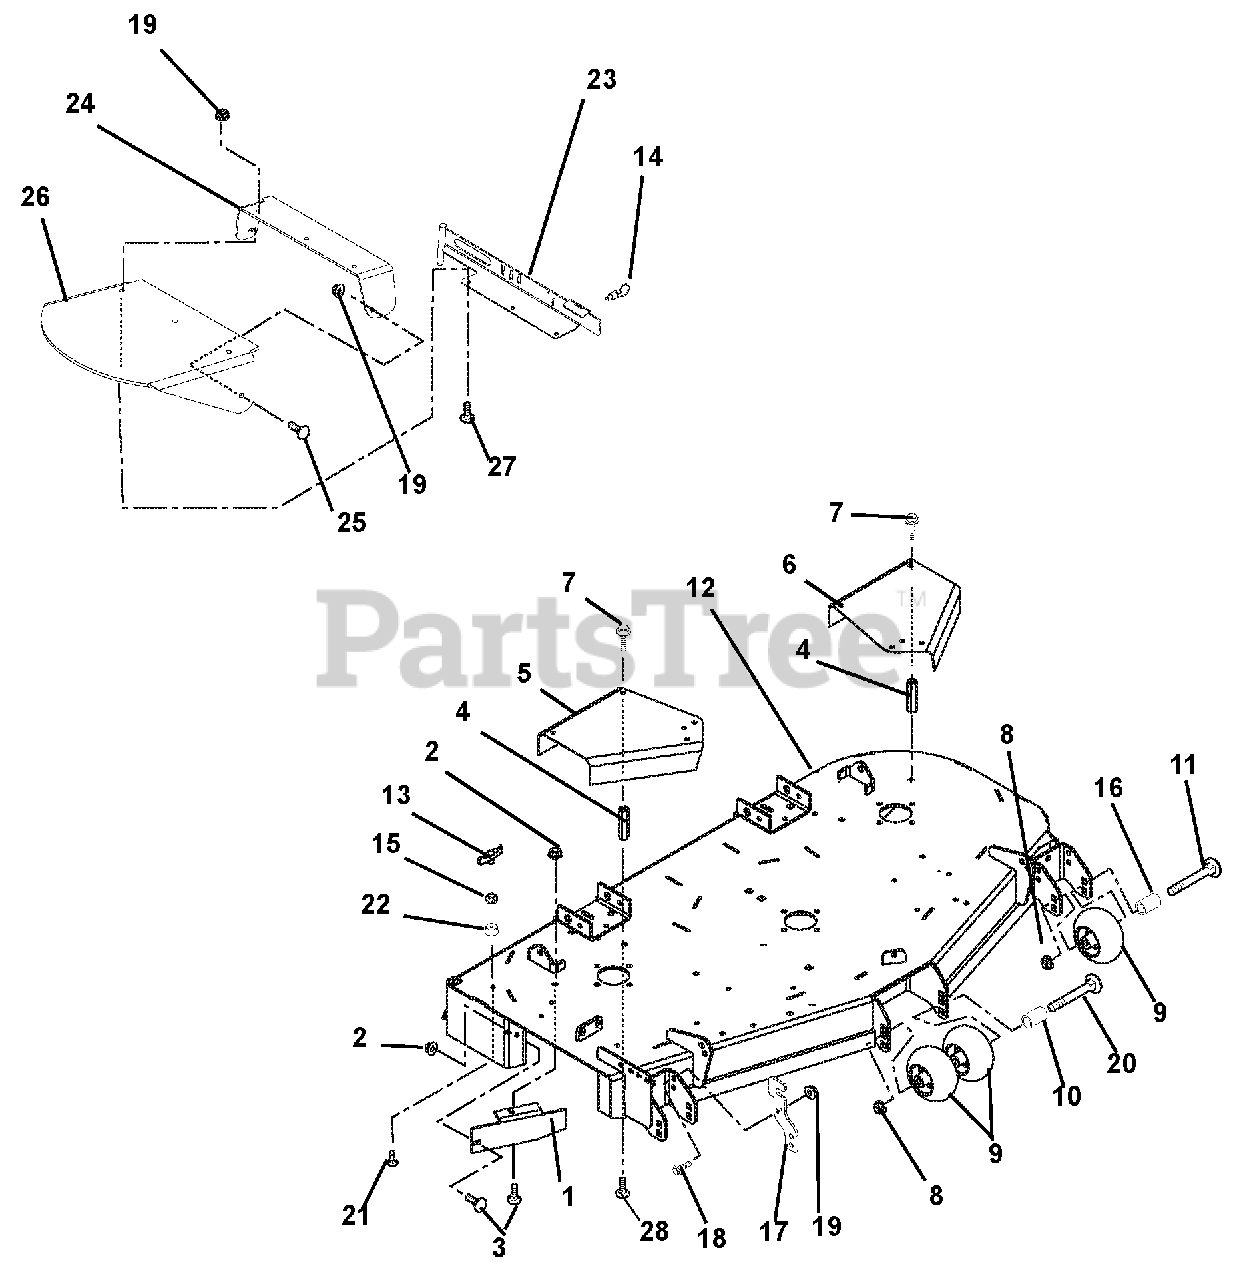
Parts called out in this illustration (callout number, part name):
1	60-in. Discharge Baffle
2	Nut, .31-18 Nyloc Flange
3	Bolt, Round Head Square Neck .31-18 x 1.00 Grade 5
4	Nut, Coupling .31-18 x 3.00
5	60-in. Right Hand Spindle Guard
6	60-in. Left Hand Spindle Guard
7	Bolt, SEMS .31-18 x .62
8	Nut .50-13 Nyloc Flange
9	Anti-Scalp Wheel
11	Bolt-Round Head Square Neck .50-13X5.00
12	60-in. Mower Deck
13	Knob, Wing .312-18
14	Pin, Plunger Pull .50-13 Thread x .310 Diameter
15	Nut, Locking, Center .31-18
16	Spacer, .510 x .625 x 3.35
17	Chute, Storage Bracket
18	Bolt, Hex .38-16 x 1.00
19	Nut, .38-16 Nyloc Flange
20	Bolt, Round Head Square Neck .50-13 x 8.50
21	Bolt, Round Head Square Neck .31-18 x 1.50
22	Bumper, Recessed 1.50 x .63, .31 Thru Hole
23	52-inch and 60-inch Discharge Chute Mounting Weldment
24	Rubber Discharge Chute Support
25	Bolt, Round Head Square Neck .38-16 x 1.00 Grade 5
26	Chute, Rubber Discharge
27	Bolt, Round Head Square Neck .38-16 x 1.25 Grade 5
28	Bolt, Round Head Square Neck .31-18 x .75
